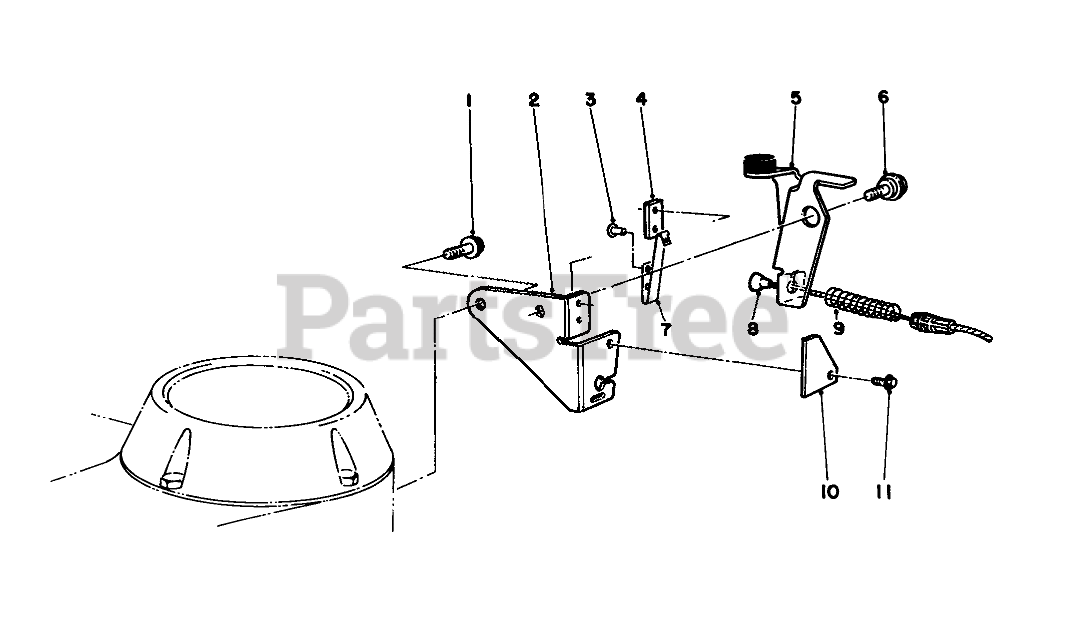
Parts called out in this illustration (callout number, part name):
1	THO FORM SCREW M6 X 1
2	PLATE-BRAKE
3	RIVET-PLASTIC
4	STRAP-INSULATING
5	BRAKE PLATE ASM
6	Screw-Shoulder
7	STRAP-GROUND
8	Cable-Brake
9	SPRING-COMPRESSION
10	STOP-GROUND STRAP
11	SCREW-HWH
